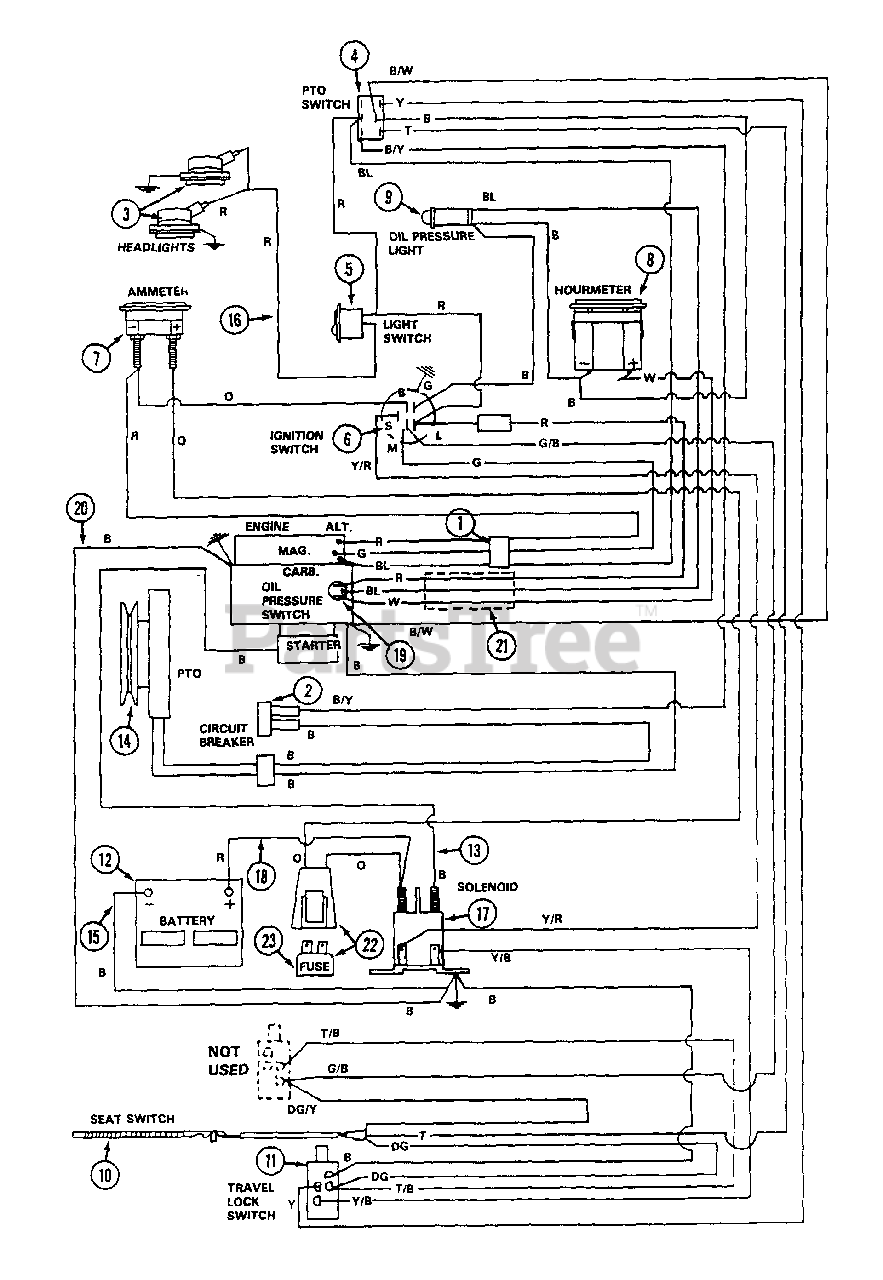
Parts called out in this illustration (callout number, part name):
1	HARNESS - wire, alternator and magneto
2	BREAKER - circuit, 10 amp
4	SWITCH - PTO (also use C31619 Cap)
5	SWITCH - headlight
6	SWITCH - ignition
9	LIGHT - oil
10	SWITCH - seat.
11	SWITCH - safety
12	BATTERY - 12 volt
13	WIRE - starter
15	CABLE - ground
16	WIRE - headlight
17	SOLENOID - start
18	CABLE - battery positive to solenoid
19	SWITCH - oil light
20	WIRE - ground
21	HARNESS - oil pressure switch
22	KIT - fuse holder
23	FUSE - 30 amp
